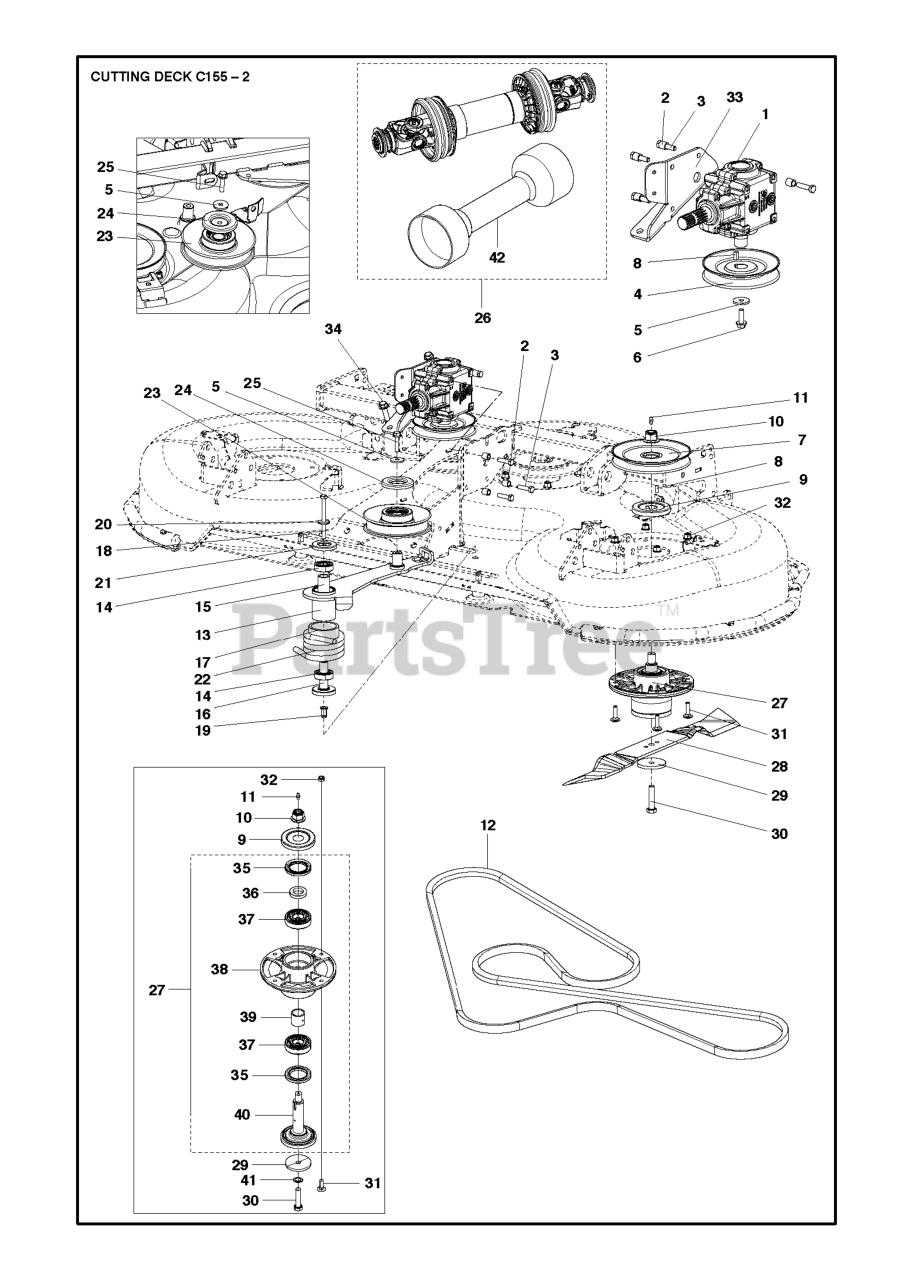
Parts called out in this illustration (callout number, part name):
11	GREASE NIPPLE
14	BALL BEARING
17	SPACER, IDLER PIVOT
19	BLIND RIVET NUT
21	DUST SHIELD
25	SCREW EHHFM
28	BLADE COMBICLIP 155 REAR DISCH
32	NUT FLANGE
37	BALL BEARING 6305 C3
